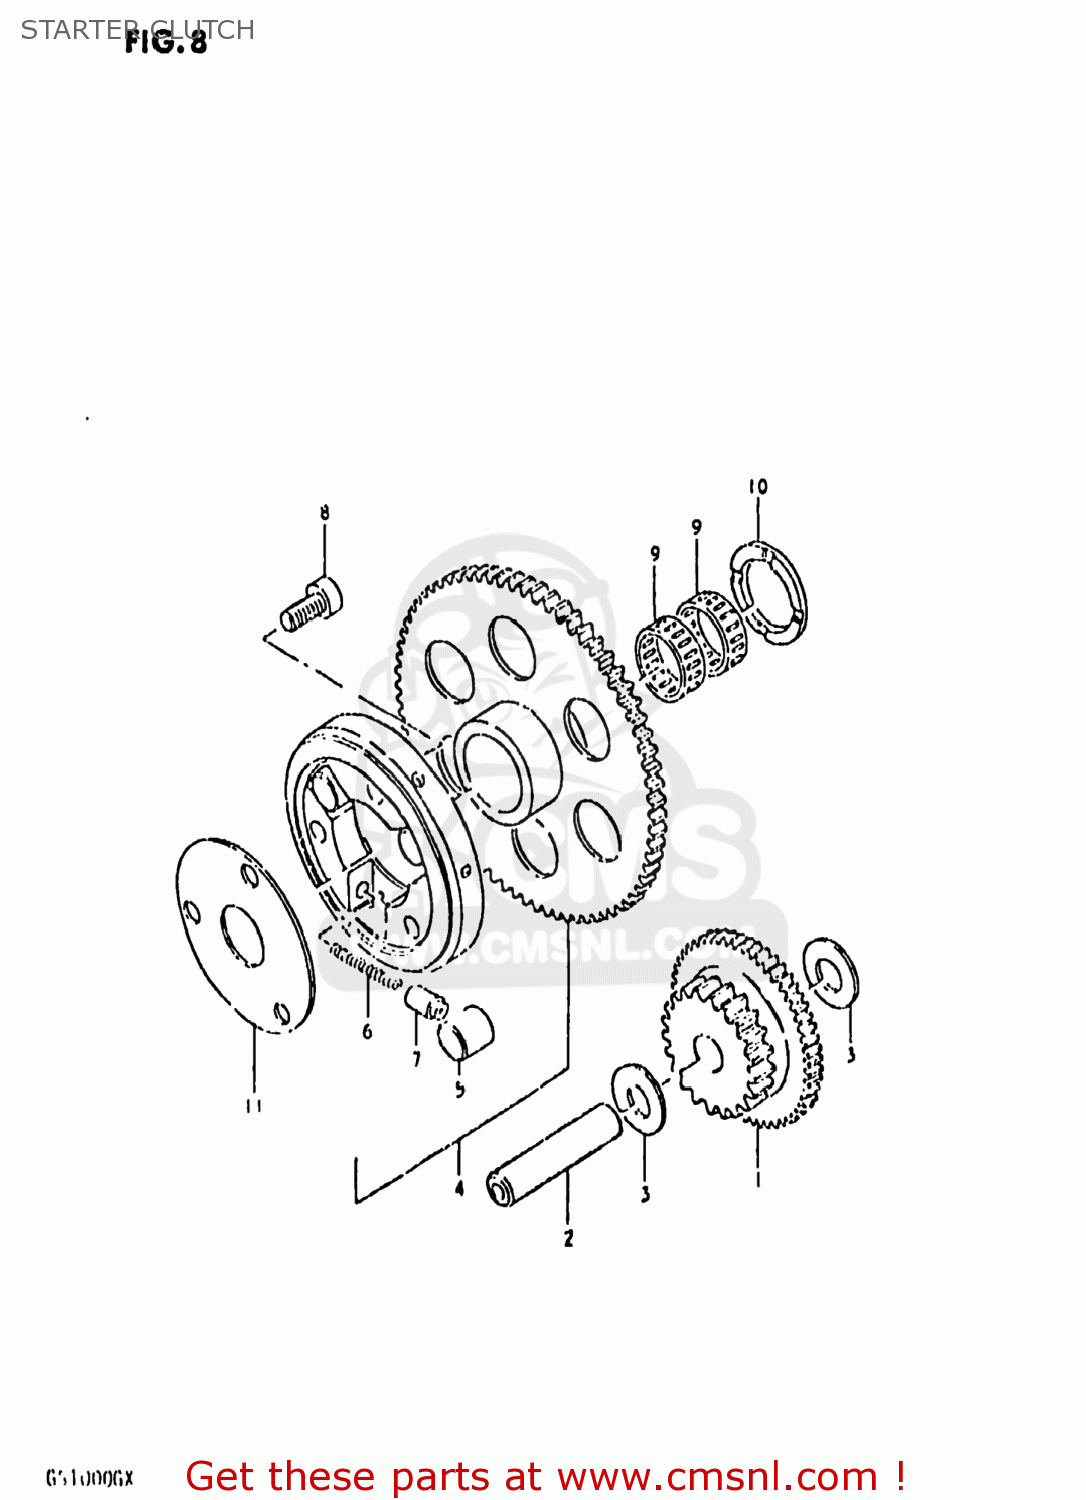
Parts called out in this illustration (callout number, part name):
1	GEAR,STARTER IDLE
2	PIN(7.4X13X56)
3	WASHER(13.3X25X0.85)
4	CLUTCH SET,STARTER
5	PIN(14X13)
6	SPRING
7	PIECE,PUSH
8	BOLT
9	ROLLER BEARING (25X30X9
10	WASHER(25X38X2.5)
11	SHIM,STARTER CLUTCH HUB
